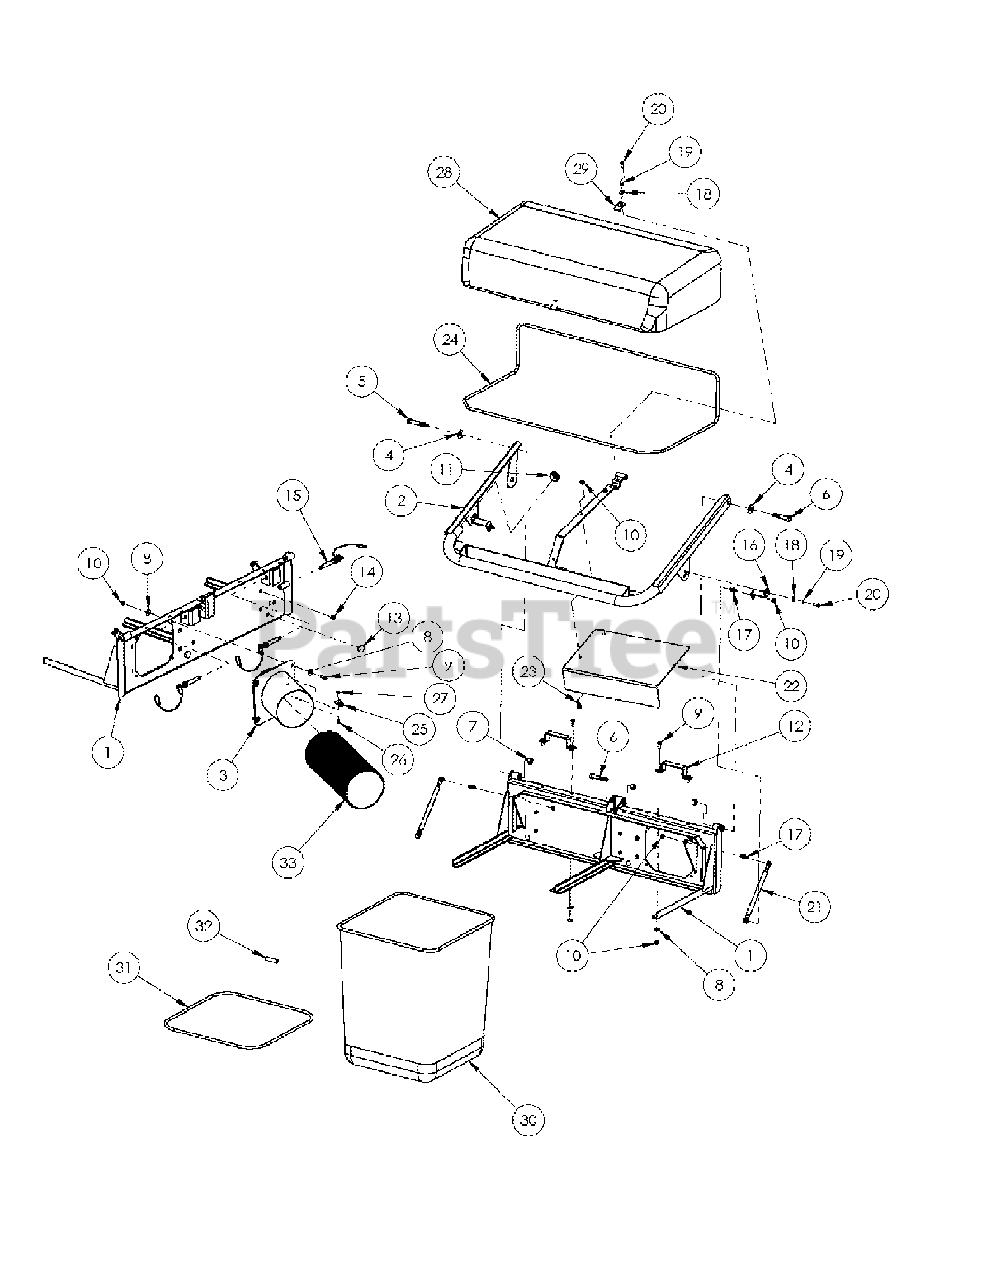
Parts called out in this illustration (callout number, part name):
1	2 BAG CATCHER BAG SUPPORT MOUNT
2	2 BAG CAP SUPPORT
3	INLET TUBE ASSEMBLY
4	FLAT WASHER-1/2
5	CAP SCREW-1/2"-13 X 3" LONG
6	CAP SCREW-1/2"-13 X 2 1/2" LONG
7	HEX NUT, NYLON INSERT-1/2"-13
8	FLAT WASHER-5/16"
9	CAP SCREW-5/16"-18 X 3/4" LONG
10	HEX NUT, NYLON INSERT-5/16-18
12	BAG HANDLE
13	RUBBER BUMPER
14	PLUG, HOLE 7/16
15	DETENT PIN W/ LANYARD-1/2" X 2 1/2" LONG
16	BRACKET-GAS CYLINDER MOUNT
17	BALL JOINT
18	1/4" WASHER
19	LOCK WASHER-1/4"
20	CAP SCREW-1/4-20 X 3/4" LONG
21	GAS CYLINDER
22	2 BAG DEFLECTOR
23	PAN HEAD SCREW-5/16"-18 X 3/4" LONG
24	AIR DOME FRAME, 2 BAG-3/8" ROD ONE PIECE
25	SPRING CLIP
26	MACHINE SCREW-#10-24 X 1/2" LONG
27	HEX NUT, NYLON INSERT-#10-24
28	2-BAG FABRIC CAP WITH "J" STRIP-PLAIN
29	BRACKET-SINGLE HOLE MOUNT
30	CATCHER BAG, COMMERICAL
31	GRASS BAG FRAME, COMMERCIAL
32	CONNECTOR TUBE
33	DISCHARGE HOSE
